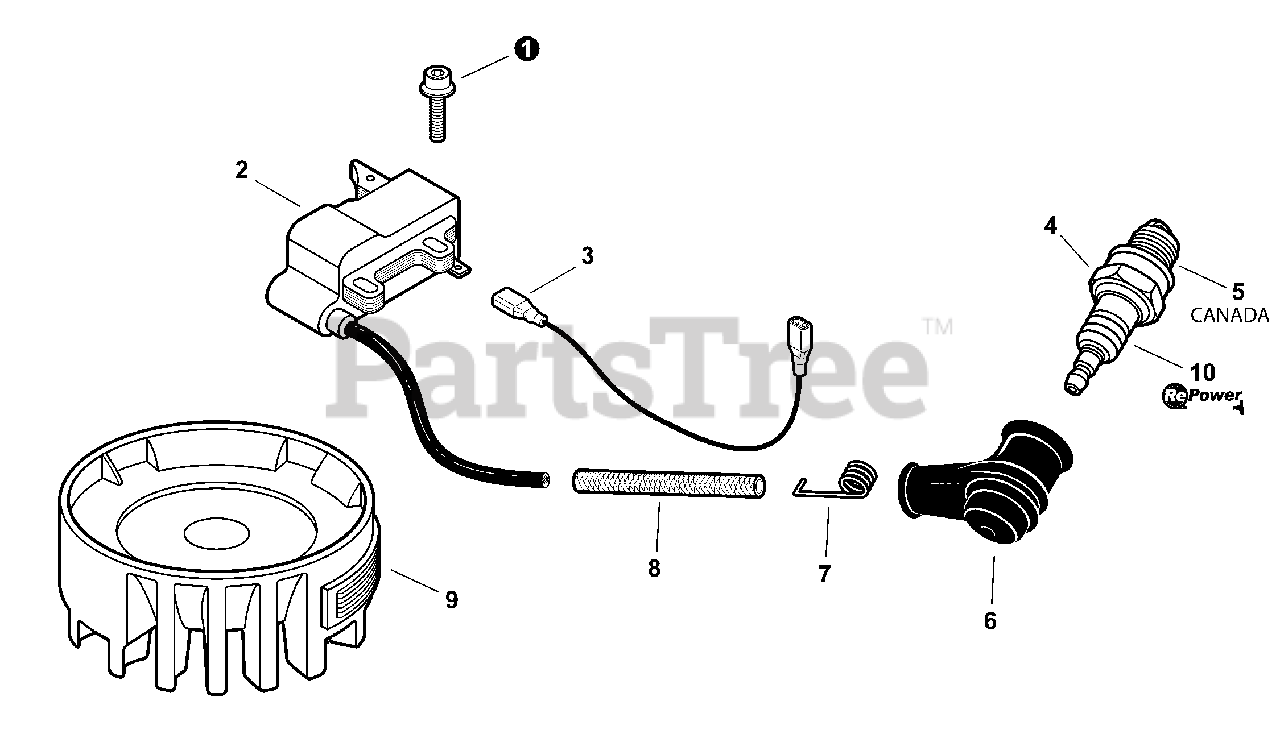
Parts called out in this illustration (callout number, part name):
1	BOLT 4×20
2	COIL, IGNITION
3	LEAD - IGNITION
4	SPARK PLUG - BPM8Y
5	SPARK PLUG - BPMR8Y
6	CAP, SPARK PLUG
7	TERMINAL, SPARK PLUG
8	TUBE, INSULATOR 7×8.6×55
9	FLYWHEEL
10	TUNE-UP KIT - REPOWER
18	TUNE-UP KIT - REPOWER
